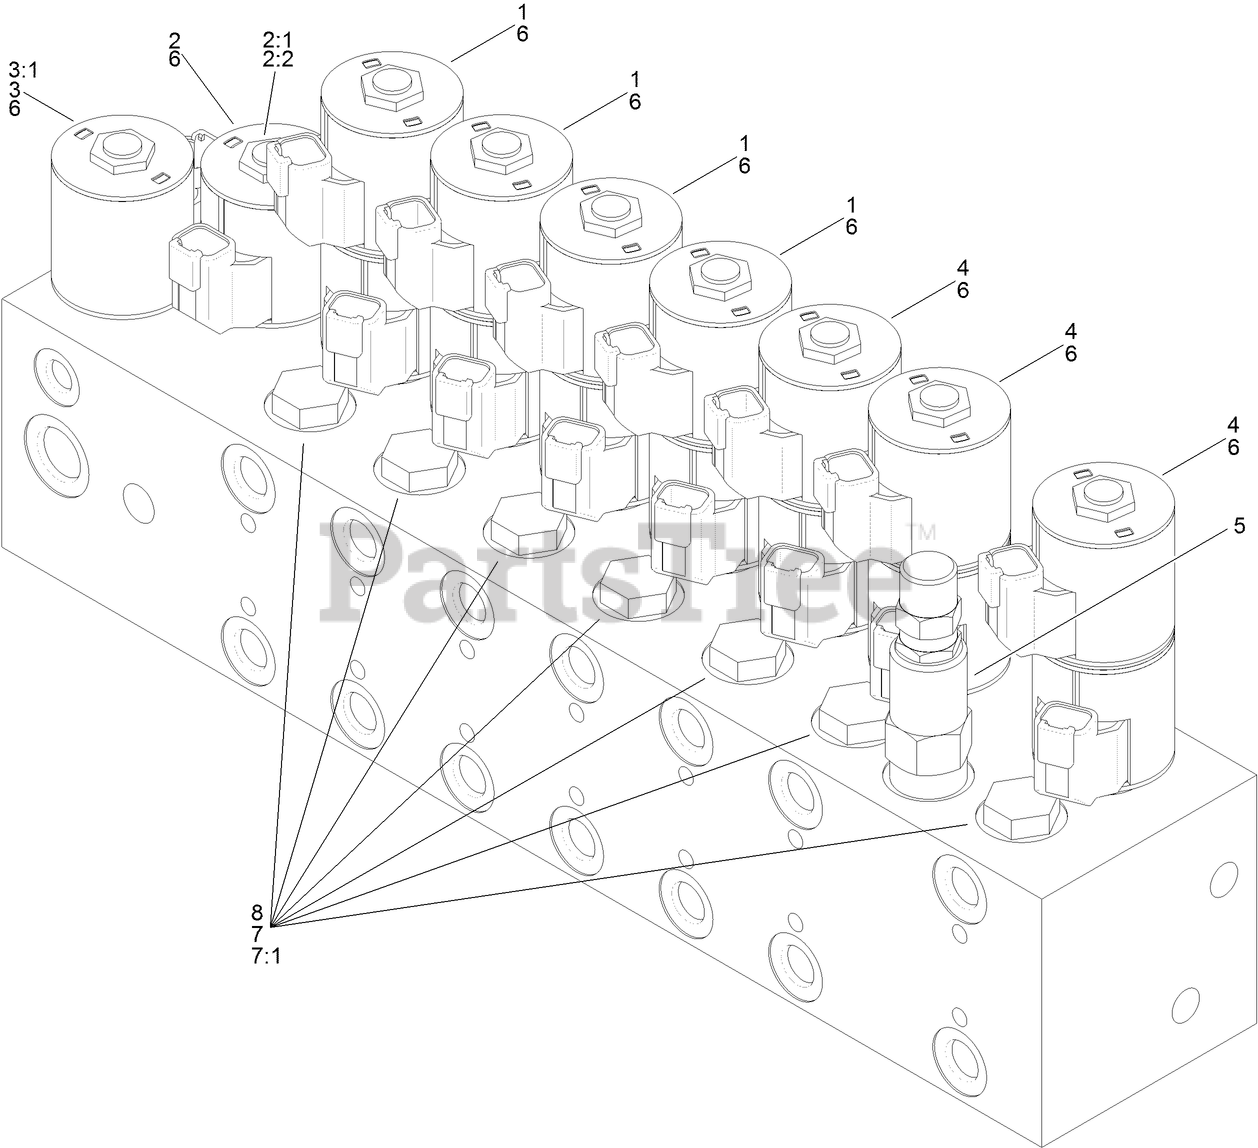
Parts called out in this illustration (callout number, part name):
1	VALVE-CARTRIDGE, MOTOR SPOOL
2	SOLENOID VALVE ASM
2:1	SEAL KIT
2:2	NUT-COIL
3	VALVE-SOLENOID
3:1	SEAL KIT
4	SOLENOID ASM
5	VALVE-REDUCING, PRESSURE
6	COIL-SOLENOID
7	CHECK VALVE ASM
7:1	SEAL KIT
8	PISTON-PILOT
